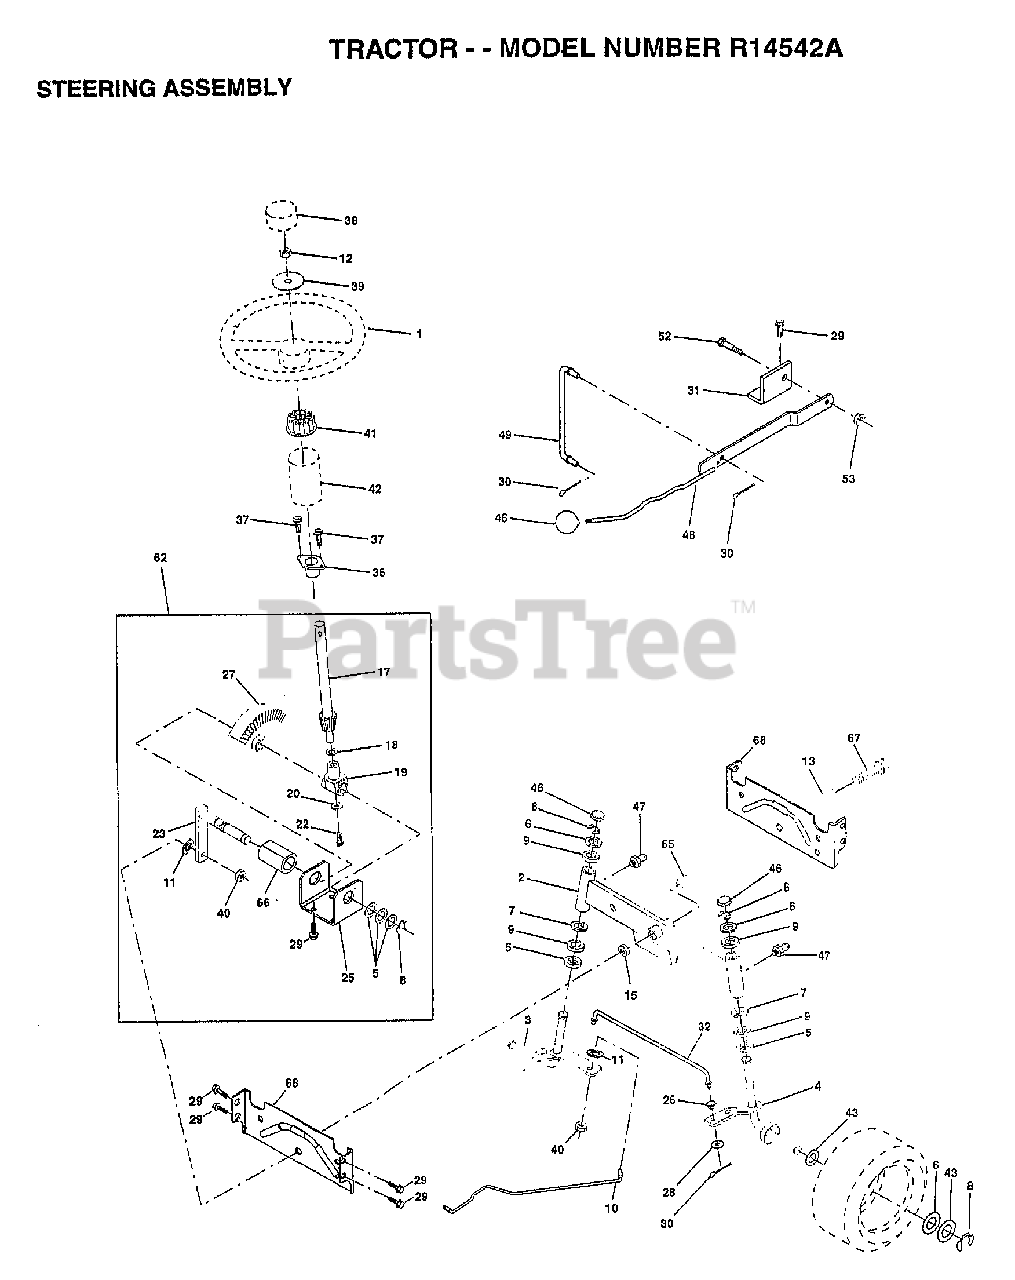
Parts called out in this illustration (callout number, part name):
2	AXLE ASM
3	SPINDLE.ASM.LH
4	"SPINDLE ASM,RH"
5	WASHER .T
6	WASHER
7	WASHER
8	RING
9	COL. SRTG. BEAR.
10	DRAGLINK-STAMPED
11	LOCKWASHER
13	BEARING AXLE
15	"NUT-LOC,FLANGE LT"
17	SHAFT ASM STEERNG
18	THRUST WASHER
19	SUPPORT.SHAFT
22	SCREW HEX SOC1/4-
25	BRKT-STEERING
26	BUSHING.DRAGLINK
27	GEAR SECTOR
28	WASHER
29	SCREW
30	COTTER PIN
31	BRKT.PVT.MAN.LVR.
32	TIE ROD
36	BUSHING.STRG.3/4
37	"SCREW-TT,10-32 FL"
38	ST WHL INSERT CAP
39	WASHER
40	GRIPCO NUT
41	ADAPTER LT
42	BOOT SHAFT STEER
43	WASHER
45	KNOB T (1/2-HOLE)
46	CAP
47	ZERK M
48	LEVER.ASM.CLUTCH
49	LINK CLTCH W/NUTS
52	"BOLT, SHOULDER LT"
62	KIT STEERING ASM
65	SPACER AXLE
66	"BEARING-ARM,PITMA"
67	BOLT
68	BRACE AXLE
